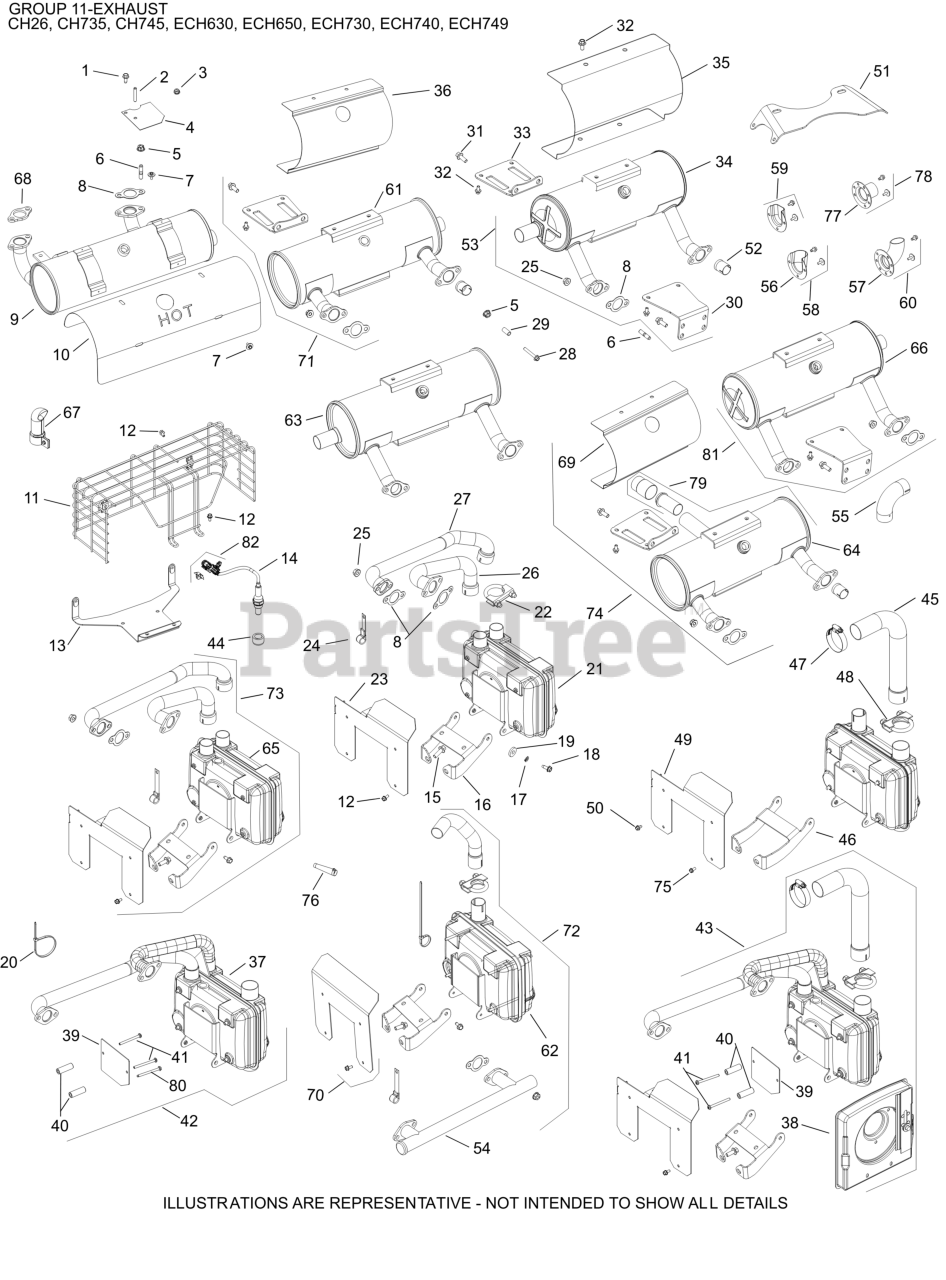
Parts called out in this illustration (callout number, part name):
5	NUT, HEX FLANGE LOCK (M8)
6	STUD, METRIC EXHAUST
8	GASKET, EXHAUST MANIFOLD
14	SENSOR, OXYGEN (M18 x 1.5 THREADS)
52	LINER, EXHAUST PORT
